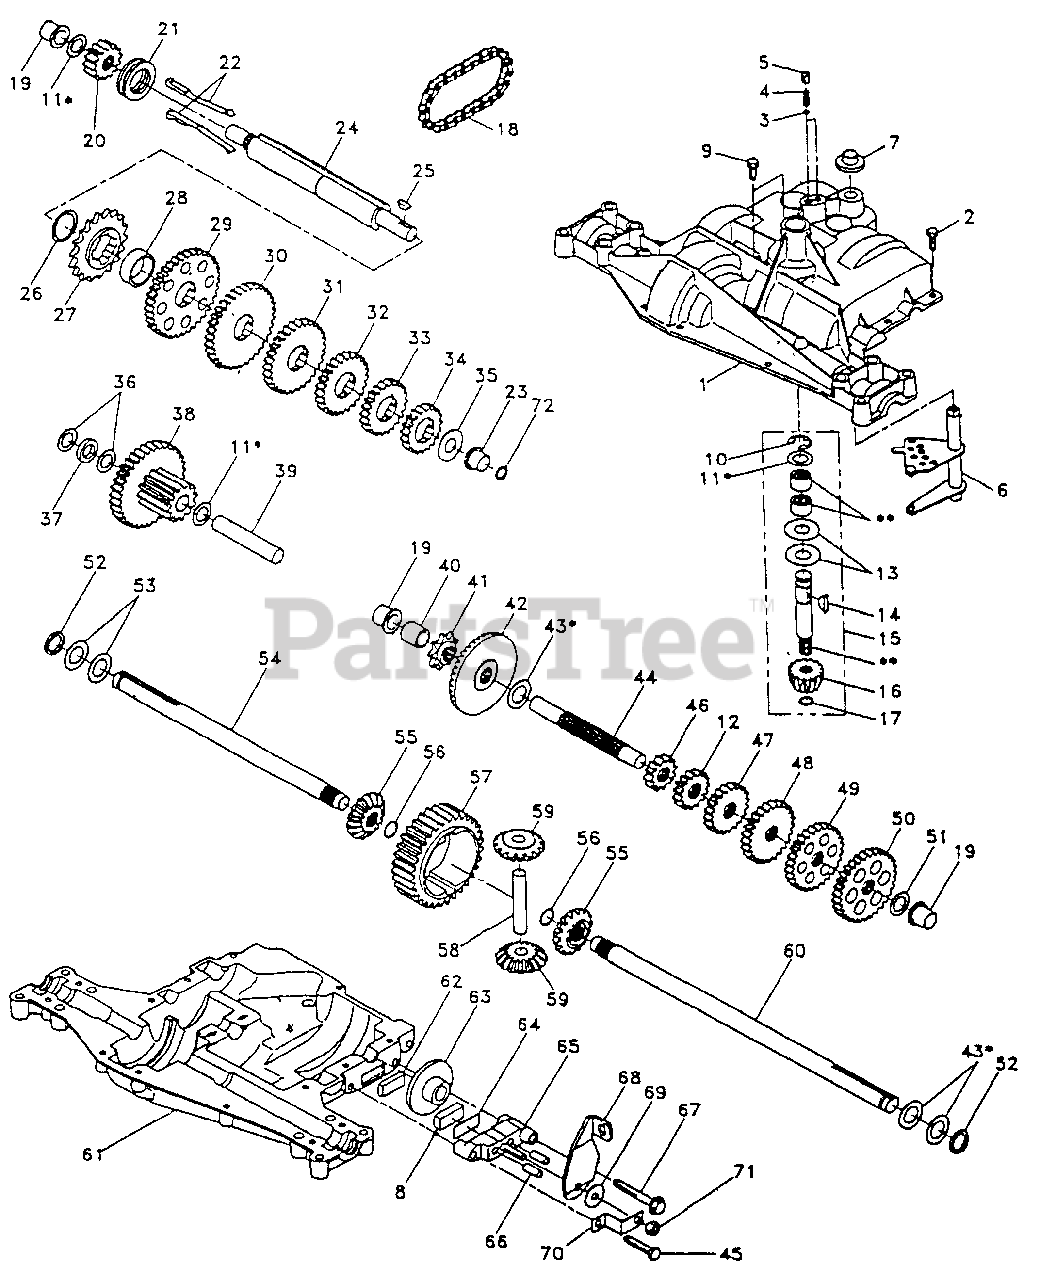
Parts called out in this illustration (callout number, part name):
1	Housing, Upper
2	Screw, Self-Tapping, Large 1/4-20 x .734
3	Ball, Detent
4	Spring, Detent
5	Screw, Set
6	Kit, Shifter Assembly
7	Boot, Shifter
8	Puck, Friction
9	Screw, Self-Tapping, with Sealer
10	Ring, Retaining
11	Assembly, Kit, Shim .625 Shaft
12	Gear, Spur, 15 Teeth
13	Washer, Plain .632 x 1.38 x .046
14	Key, Woodruff, #9
15	Assembly, Kit, Input Shaft
16	Pinion, Bevel, 14 Teeth
17	Ring Retaining
18	Chain, 24 Pitches
19	Bearing, Flange
20	Gear, Spur, 14 Teeth
21	Collar, Clutch
22	Assembly, Kit, Clutch Keys
23	Bearing, Flange
24	Shaft, Intermediate
25	Key, Woodruff, #61
26	Ring, Retaining
27	Sprocket, 18 Teeth
29	Gear, Spur, 37 Teeth
30	Gear, Spur, 35 Teeth
31	Gear, Spur, 30 Teeth
32	Gear, Spur, 25 Teeth
33	Gear, Spur, 22 Teeth
34	Gear, Spur, 19 Teeth
35	Washer, Plain .640 x 1.37 x .061
36	Washer, Plain .632 x 1.00 x .026
37	Spacer .630 x 1.00 x .169
38	Assembly, Gear, Combination of 12 Teeth and 35 Teeth
39	Shaft, Idler
40	Spacer .635 x .875 x .755
41	Sprocket, 9 Teeth
42	Gear, Bevel, 42 Teeth
43	Assembly, Kit, Shim .750 Shaft
44	Shaft, Drive
45	Screw, Self-Tapping, Large 5/16-18 x 1.44
46	Gear, Spur, 12 Teeth
47	Gear, Spur, 20 Teeth
48	Gear, Spur, 25 Teeth
49	Gear, Spur, 28 Teeth
50	Gear, Spur, 31 Teeth
51	Washer, Plain .632 x -1.00 x .060
52	Washer, Neoprene
53	Washer, Plain .758 x 1.25 x .031
54	Axle, L.H.
55	Gear, Miter, 15 Teeth
56	Ring, Retaining
57	Gear, Spur, 32 Teeth
58	Shaft, Cross
59	Gear, Miter, 15 Teeth
60	Axle, R.H.
61	Housing, Lower
62	Puck, Friction
63	Disc, Brake
65	Jaw, Brake
66	Pin, Dowel
67	Screw, Self-Tapping, Large 5/16-18 x 2.25
68	Lever, Actuating
69	Washer, Plain .321 x 1.00 x .055
70	Bracket, Anti-Rotation
71	Locknut 5/16-24
73	Grease
